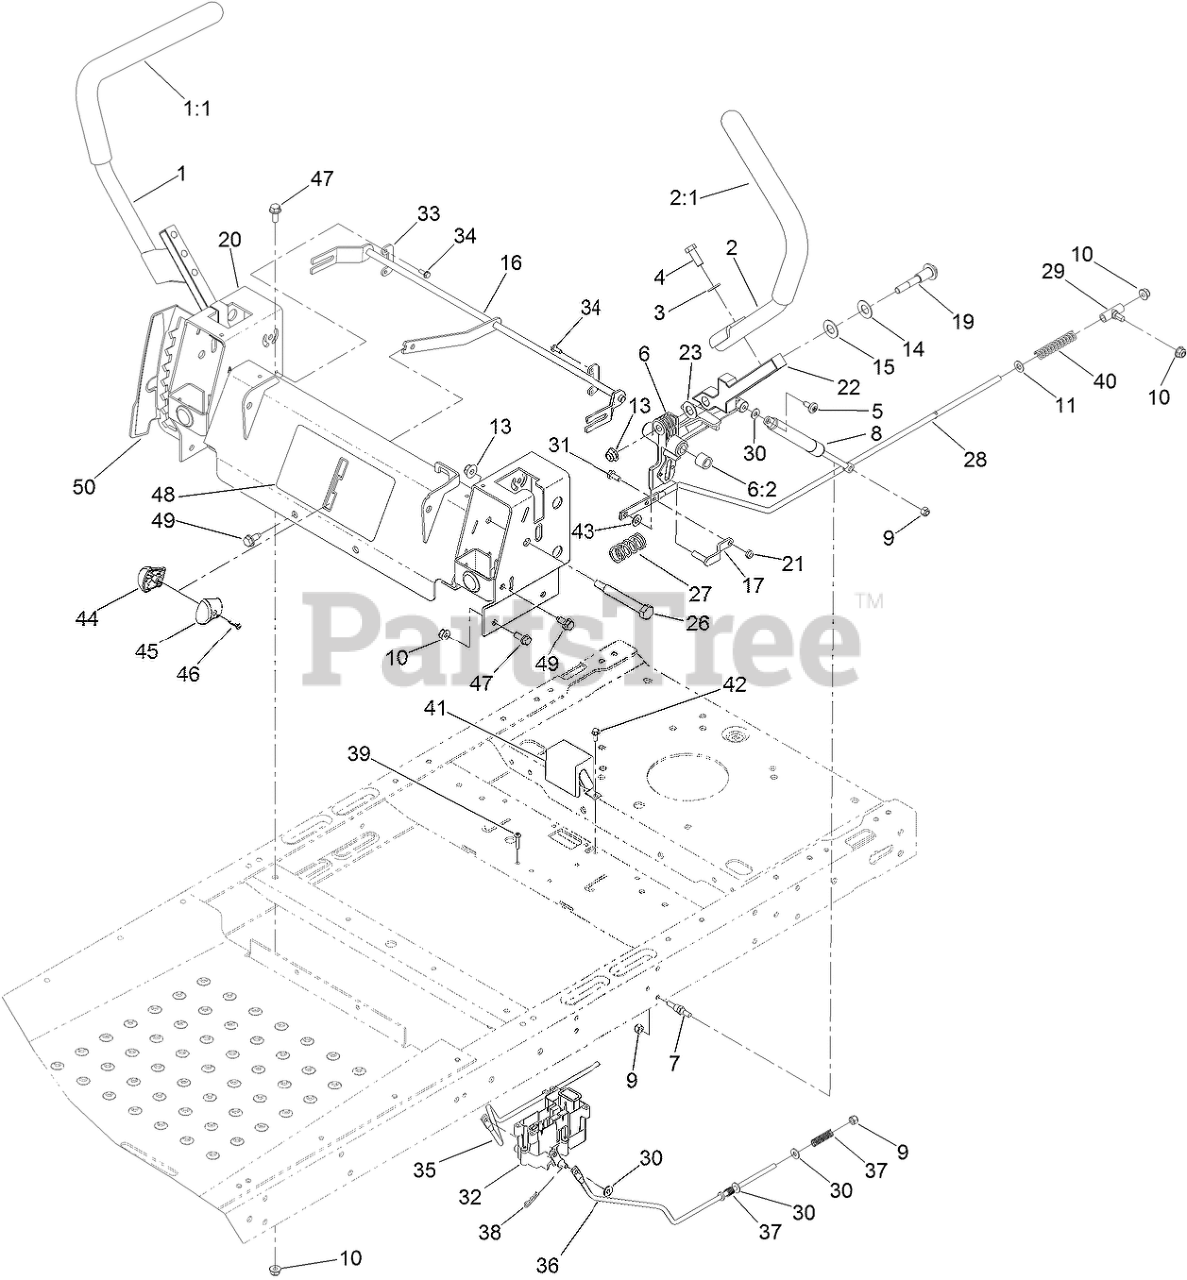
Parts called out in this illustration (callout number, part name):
1	HANDLE-CONTROL, RH
2	HANDLE-CONTROL, LH
3	WASHER-FLAT
4	SCREW-HH
5	SCREW-SHOULDER
6	ACTUATOR ARM ASM
6:2	BUSHING-FLANGE
7	STUD-DAMPER
8	Damper-Control, Motion
9	NUT-LOCK, NI
10	NUT-HF, NI
11	WASHER-PLAIN
13	NUT-HF, NI
14	WASHER-BELLEVILLE
15	WASHER
16	CONTROL-SPEED
17	PIN-ROD, HYDRO
19	BOLT-PIVOT
20	CONTROL BOX ASM
21	NUT-LOCK, NI
22	LEVER-CONTROL
23	WASHER-NYLON
26	BOLT-PIVOT
27	SPRING-RETURN
28	ROD-HYDRO
29	MOUNT-ROD, HYDRO
30	WASHER
31	SCREW-HH
32	BRAKE CONTROL MODULE ASM
33	RETAINER
34	SCREW-TAPTITE
35	ROD-BRAKE, WIDE (RH)
36	ROD-BRAKE, WIDE (LH)
37	SPRING-COMPRESSION
38	PIN-COTTER
39	SCREW-PPH
40	SPRING-RETURN, NEUTRAL
41	COVER-BRAKE
42	SCREW-HWH
43	SPACER-NYLON
44	KNOB-RH
45	KNOB-LH
46	SCREW-PPH
47	SCREW-HHF
48	DECAL-SPEED CONTROL
49	SCREW-HWHTF
50	DECAL-HOC
